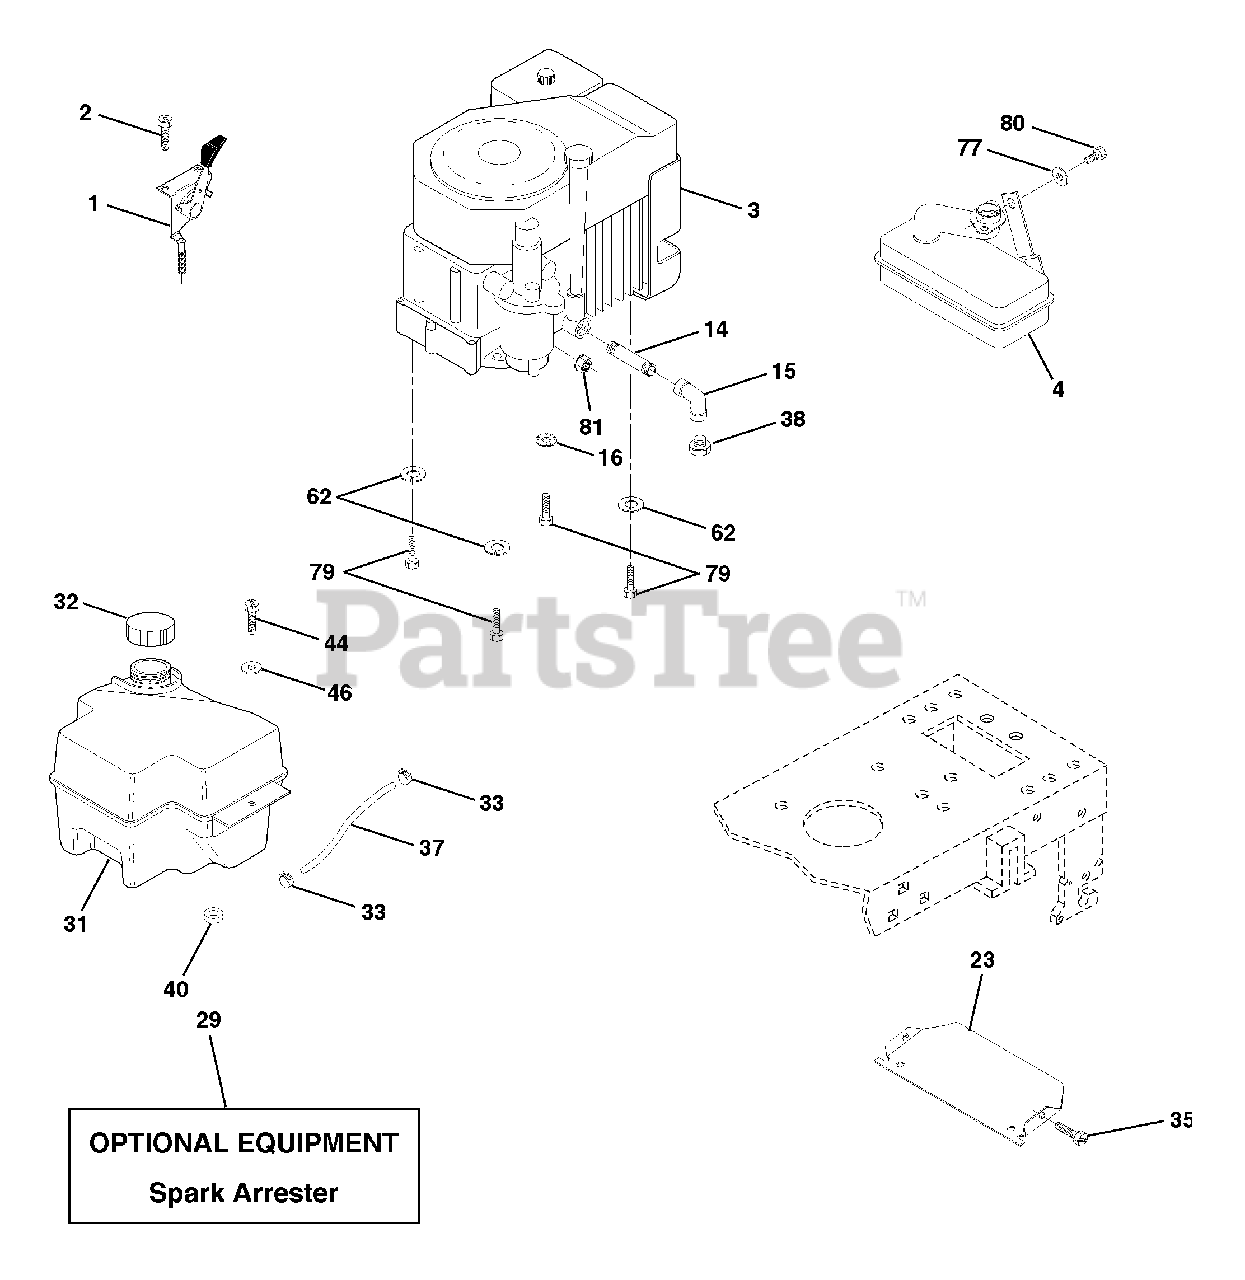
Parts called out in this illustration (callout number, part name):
1	Control THTICH 27 LH FLAG DOM
2	Screw Hex Thd Cut 1/4-20 x 5/8 T
3	Engine Kohler, Model No. CV15S 15 HP
4	Muffler LT Kohler 12.5/15HD
14	Nipple Pipe 3/8 Npt X 3-1/2
15	Elbow Std 90 Degree 3/8-18 Npt
16	Washer Lock Ext Tooth 5/16
23	Shield Heat
29	Kit Spark Arrestor (Flat Scrn)
31	Tank Fuel Front 2 00
32	Cap Asm Fuel W/sym Vented
33	Clamp Hose Black
35	Screw
37	Line Fuel 20"
38	Plug Oil Drain
40	Bushing Snap Nyl Blk Fuel Line
44	Screw Hexwsh Thdrol 1/4-20 x 3/4
46	Washer 9/32 X 7/8 X 16 Ga
62	Washer Lock Hvy Hlcl Spr 5/16
77	Washer 5/16 x 3/4 x 16 Ga.
79	Bolt Hex
80	Bolt Hex Hd 5/16-18 UNC x 1/2
81	Nut Flange 1/4-20 Starter Nut
